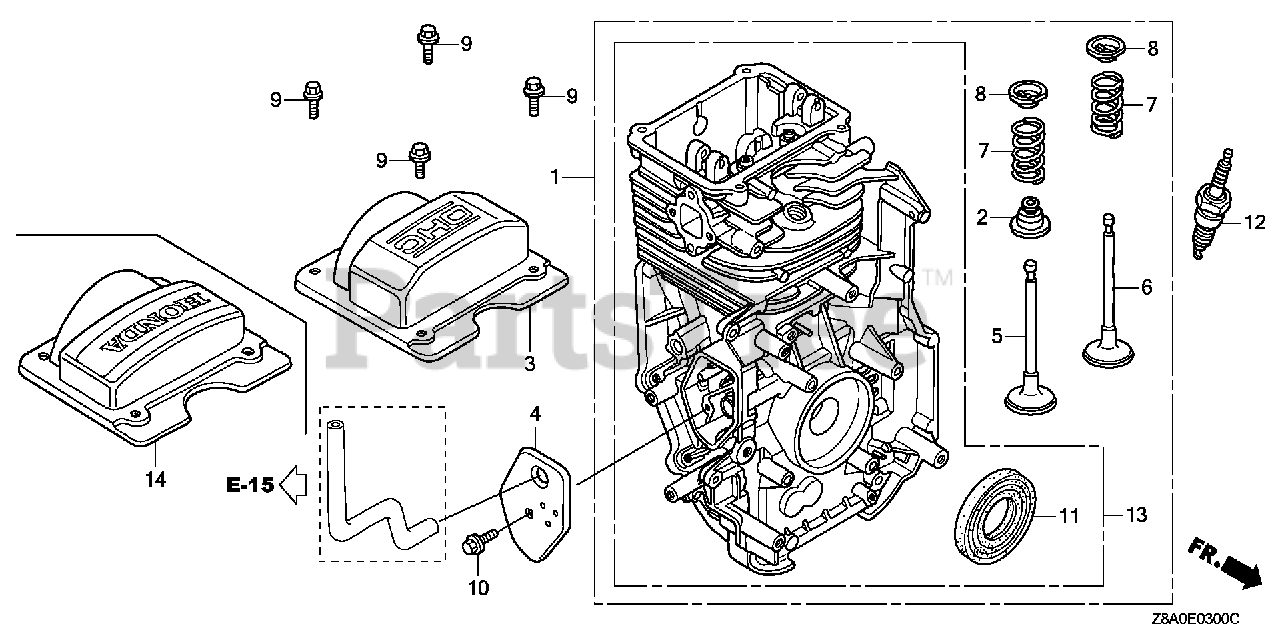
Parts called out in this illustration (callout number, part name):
1	CYLINDER ASSY.
2	SEAL, VALVE STEM
3	COVER, CYLINDER HEAD
3	COVER, HEAD
4	COVER, BREATHER (BREATHER VALVE ASSY.)
5	VALVE, IN. (TECHNOSTAR)
5	VALVE, IN. (ROCKNEL)
5	VALVE, IN.
6	VALVE, EX. (L8E)
6	VALVE, EX. (C8E)
7	SPRING, VALVE
8	RETAINER, VALVE SPRING
9	BOLT, FLANGE (6X12) (CT200)
10	BOLT, FLANGE (6X14) (CT200)
11	OIL SEAL (25.4X62X6)
12	SPARK PLUG (BPR6ES) (NGK)
14	COVER, HEAD
